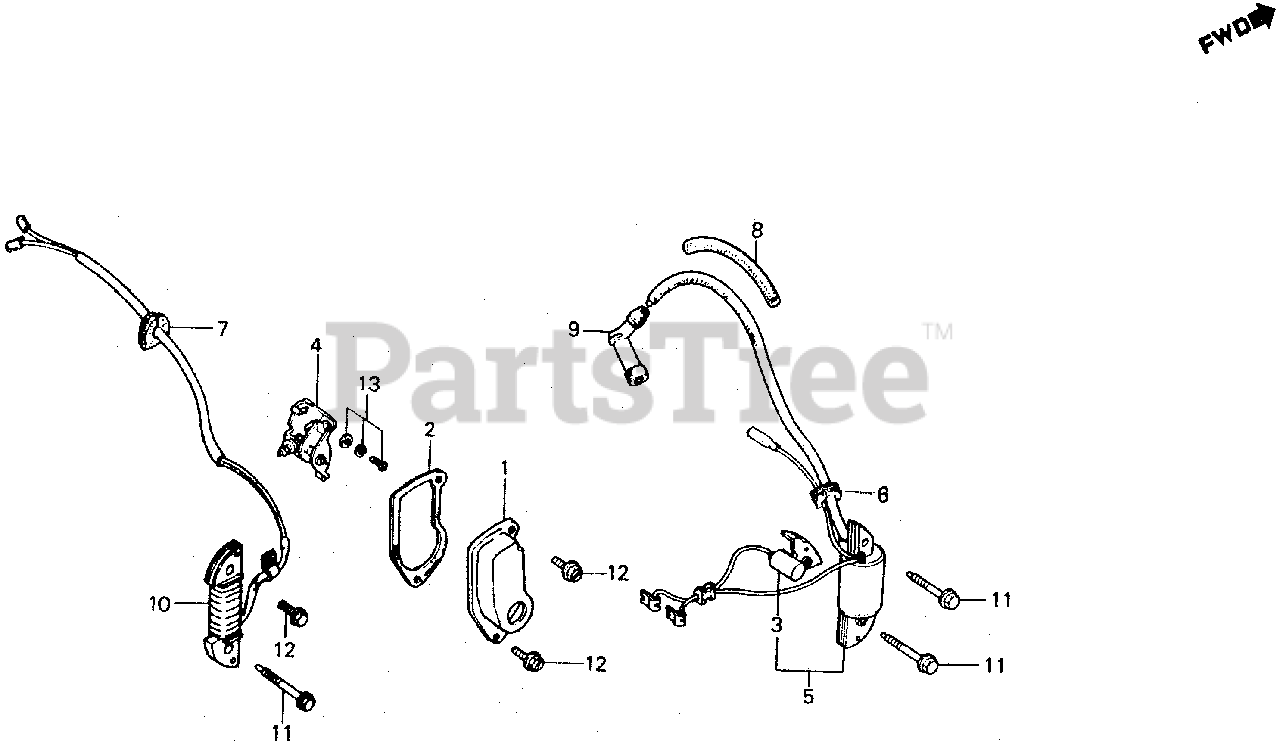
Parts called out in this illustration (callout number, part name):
1	COVER, POINTS
2	GASKET, POINT COVER
4	POINTS ASSY.
5	COIL ASSY., IGNITION (NOT AVAILABLE)
6	GROMMET, WIRE
7	GROMMET, WIRE
8	TUBE, IGNITION RUBBER
9	CAP ASSY., NOISE SUPPRESSOR
10	COIL ASSY., BACK-UP
11	BOLT, FLANGE (6X32)
12	BOLT, FLANGE (5X10)
13	SCREW-WASHER (5X12)
